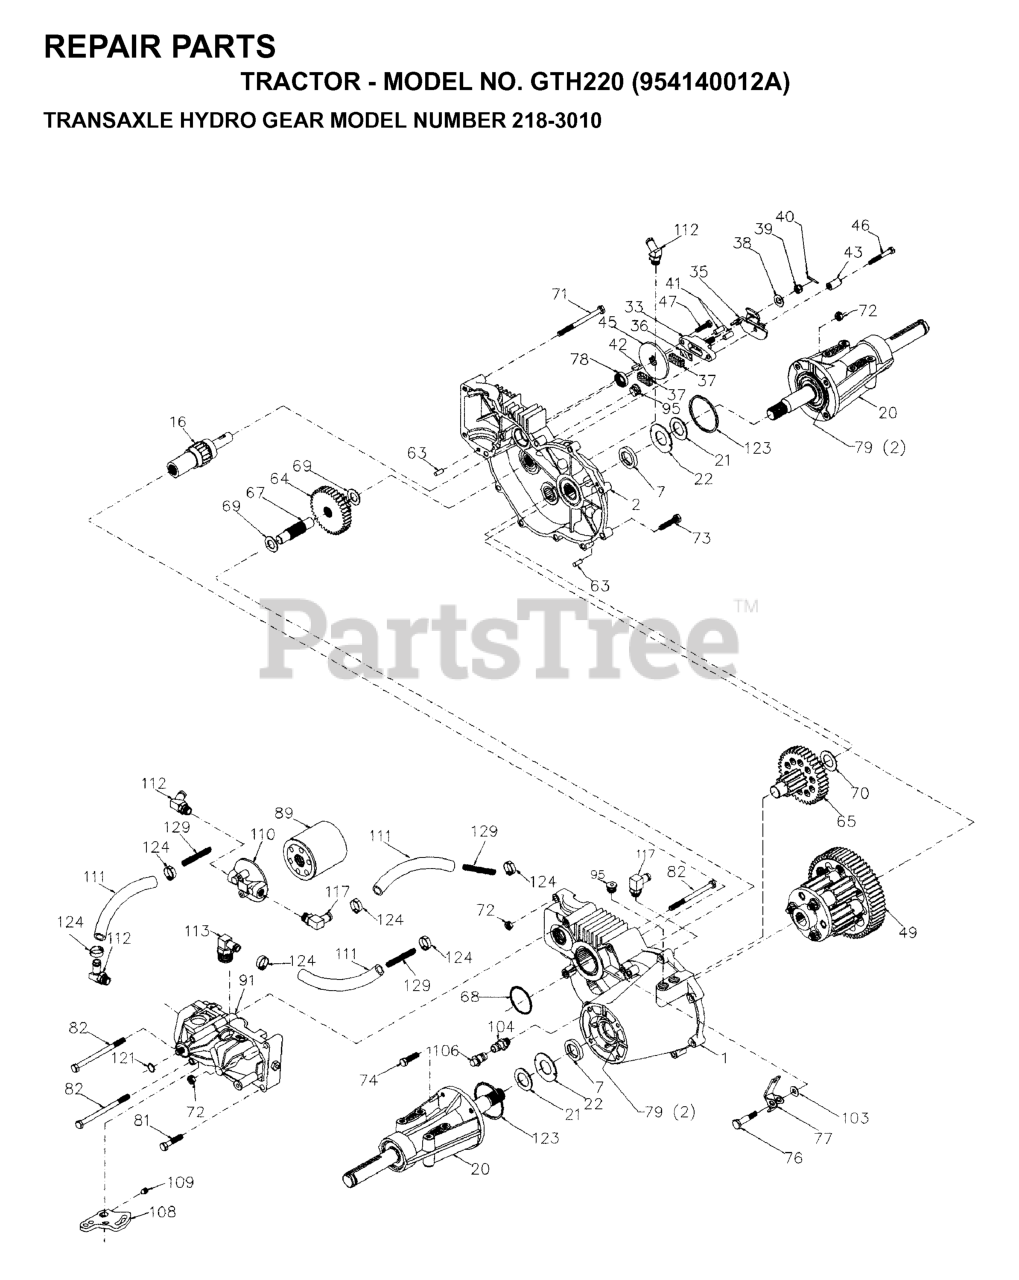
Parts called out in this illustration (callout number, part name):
7	SEAL.OIL.44782.HY (44782)
16	BRAKE SHAFT KIT #62877
36	PUCK PLATE 44134
37	BRAKE PUCK (44132)
38	WASHER .34X.88X.06.44130
39	CASTLE NUT
40	PIN.COTTER.44101.
41	BRAKE PIN 44127
47	BOLT W/NYLOCK 44433
67	JACKSHAFT.44779.HYDRO
68	O-RING #44781
72	NUT 5/16-18 HEX LOCK 43064
78	SEAL OIL 70719
89	FILTER
91	PUMP.BDU-10L-122
104	CAP, VENT ASSY
106	O-RING KIT 70110
109	SCREW.SET.50018
123	O-RING 50405
